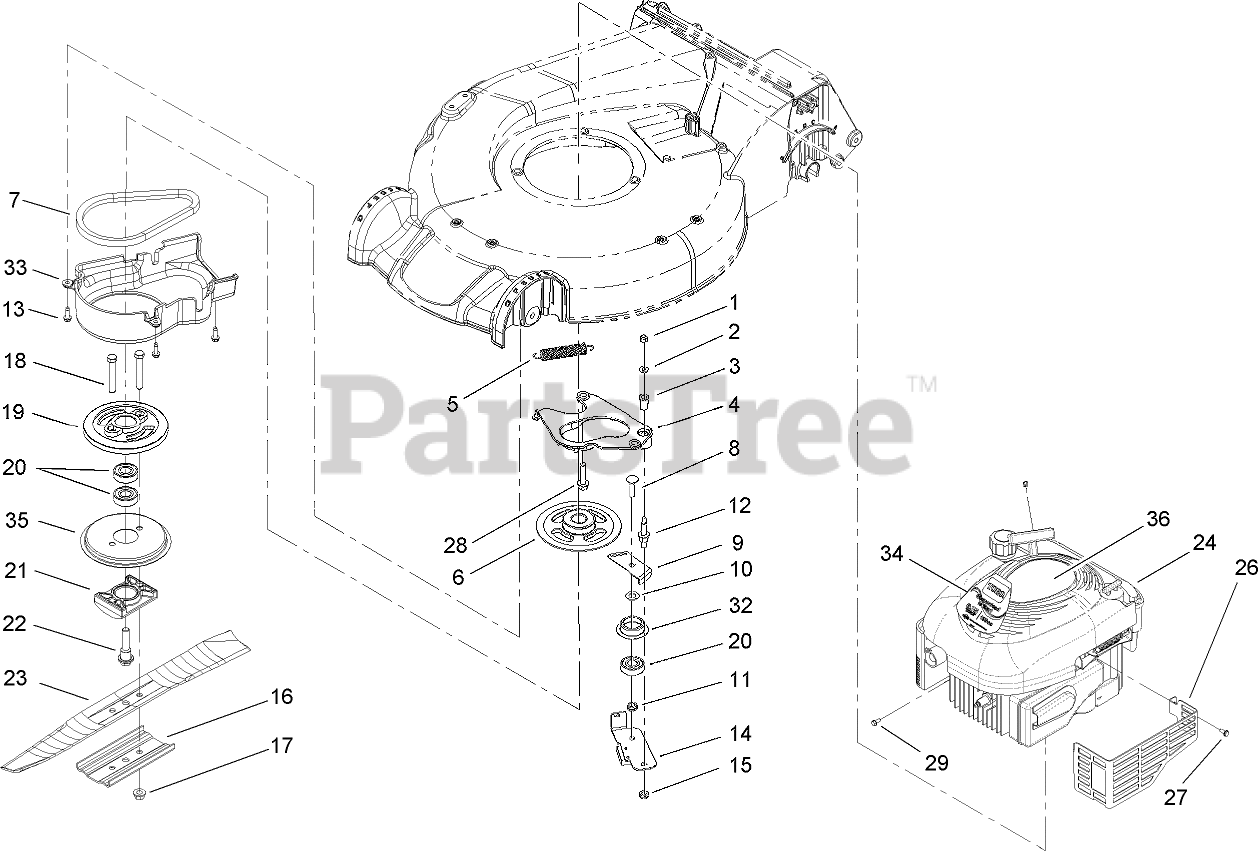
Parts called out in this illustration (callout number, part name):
1	NUT-LOCK, NI
2	WASHER-FLAT
3	BUSHING
4	PLATE-ANCHOR
5	SPRING-TENSION, BRAKE
6	PULLEY
7	BELT
8	BOLT-CARR
9	PLATE-GUIDE
10	WASHER-PLAIN
11	SPACER-BEARING
12	BOLT-SHOULDER
13	SCREW-HWHTF
14	BRAKE ARM ASM
16	SUPPORT-BLADE
17	NUT-LOCK
18	SCREW-HH
19	DRUM
20	BEARING-BALL
21	SUPPORT-BLADE
22	BOLT-CRANK
23	BLADE-RECYCLING
23	BLADE-BAGGING
26	SHIELD-MUFFLER
27	SCREW-TAPTITE
28	SCREW-HWH
29	SCREW-HWH
32	RETAINER-BELT
34	DECAL-ENGINE
35	DISC
36	DECAL-RECOIL
